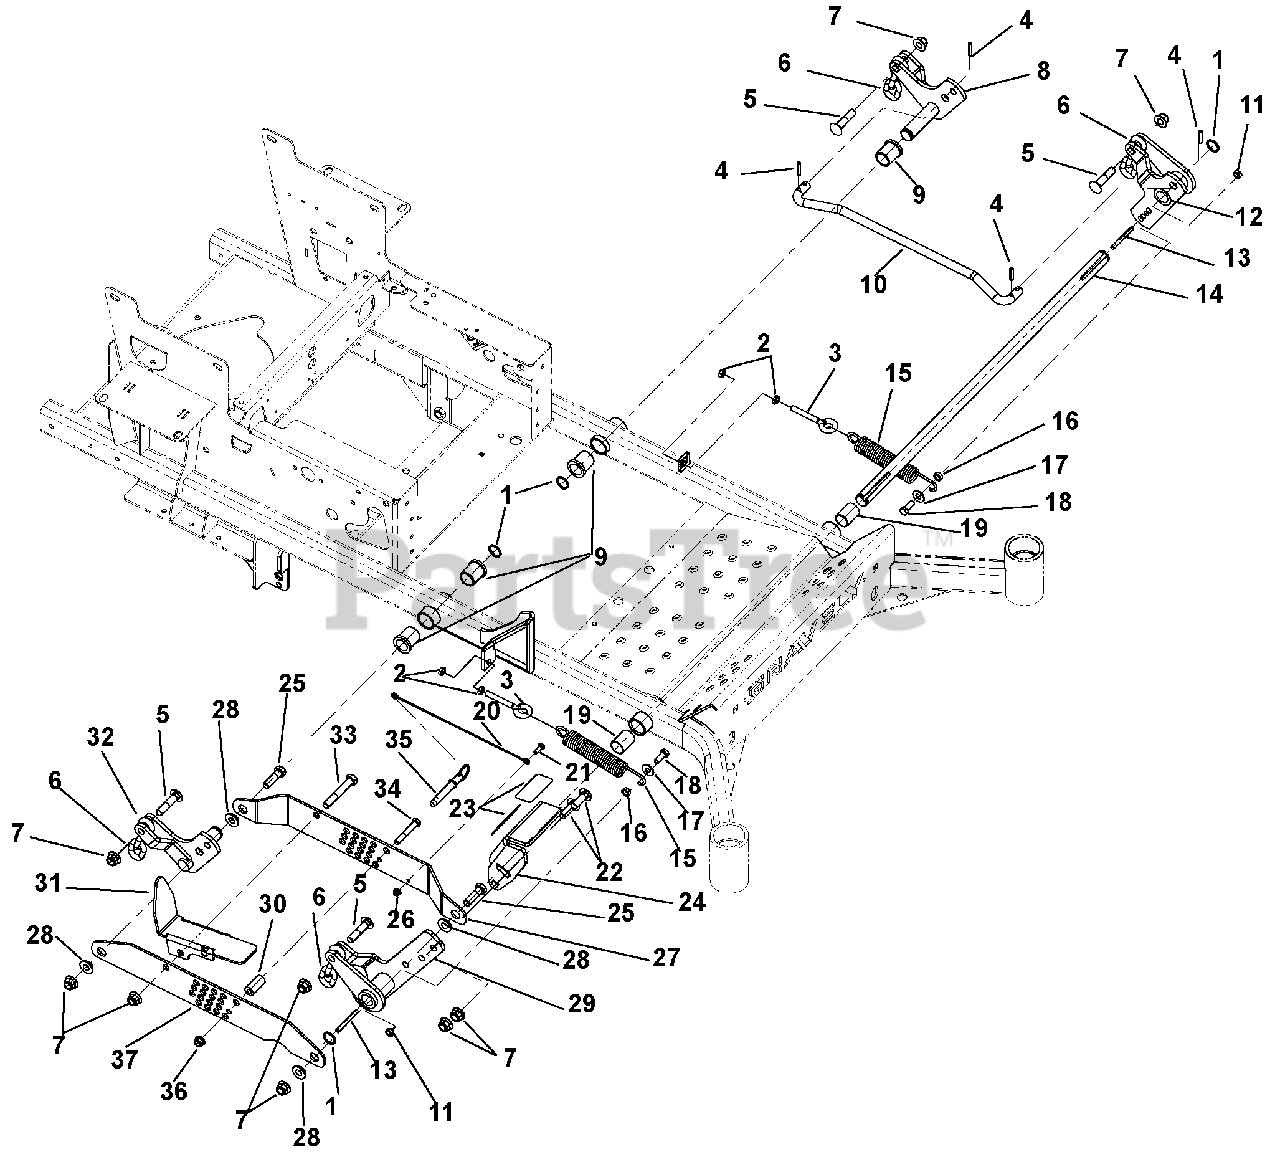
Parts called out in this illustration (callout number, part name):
1	Ring, Retaining, External 1.00 x .078
2	Nut, Hex, Jam .375-16
3	Bolt, Eye .375-16 x 2.50
4	Pin, Roll .25 x 1.25 Stainless Steel
5	Bolt, Round Head Square Neck .50-13 x 2.25
6	Chain, 3-Link .38 Deck Lift
7	Nut, Locking Nyloc Flange .50-13
8	Weldment, Rear Deck Lift Left Hand
9	Bushing, Flange 1.00 x 1.25 x 1.50 x 1.50
10	Rod, Lift Assist 19.35"
11	Nut, Locking Center Jam .375-16
12	Weldment, Front Deck Lift Left Hand
13	Key, Square .25 x 2.50 x .25 SAE
14	Shaft, PT100 Front Mower Lift
15	Spring, Tension .162 x 1.25 x 8.25 Weldment 25
16	Bushing, Sleeve .377 x .624 x .235
17	Washer, Flat Steel .438 x 1.00 x .083
18	Bolt, Hex .38-16 x 1.00
19	Bushing, 1.00 ID x 1.125 OD x 1.50
20	Cable, 12.0 Lanyard, Nylon
21	Bolt, Hex .25-20 x .75
22	Bolt, Round Head Square Neck .50-13 x 1.50
23	Grip, Pedal 1.50 x 3.00
24	Adjustable Foot Lift Pedal, Black
25	Bolt, Hex .50-13 x 1.75
26	Nut, Locking Nylon Flange .25-20
27	Lift/Cut Height Bracket, Inboard Right Hand
28	Bushing, Flange .515 x .750 x .395 x 1.120
29	Weldment, Adjustable Deck Foot Lift
30	Spacer, .375 x .750 x 1.54
31	Mechanical Lock-up Weldment, Black
32	Weldment, Rear Deck Lift Right Hand
33	Bolt, Hex .50-13 x 3.25
34	Bolt, Hex .38-16 x 2.50
35	Pin, .50 x 2.00 Usable Length Ball
36	Nut, Locking Nyloc Flange .38-16
37	Lift/Cut Height Bracket, Outboard Right Hand
